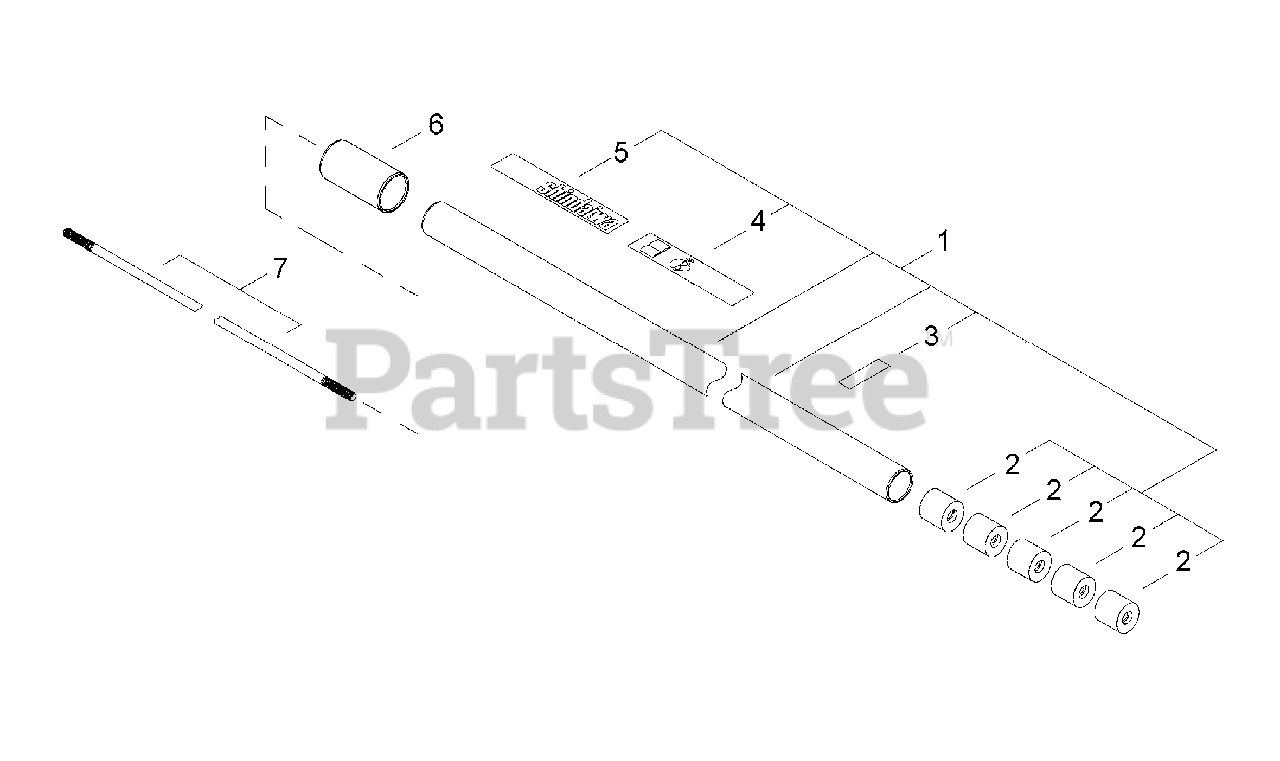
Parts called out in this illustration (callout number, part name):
1	MAIN PIPE ASSY
2	BUSHING
3	LABEL - INSTRUCTION
4	LABEL - CAUTION
5	LABEL - TRADE
6	CAP, MAIN PIPE
7	PIPE, MAIN
